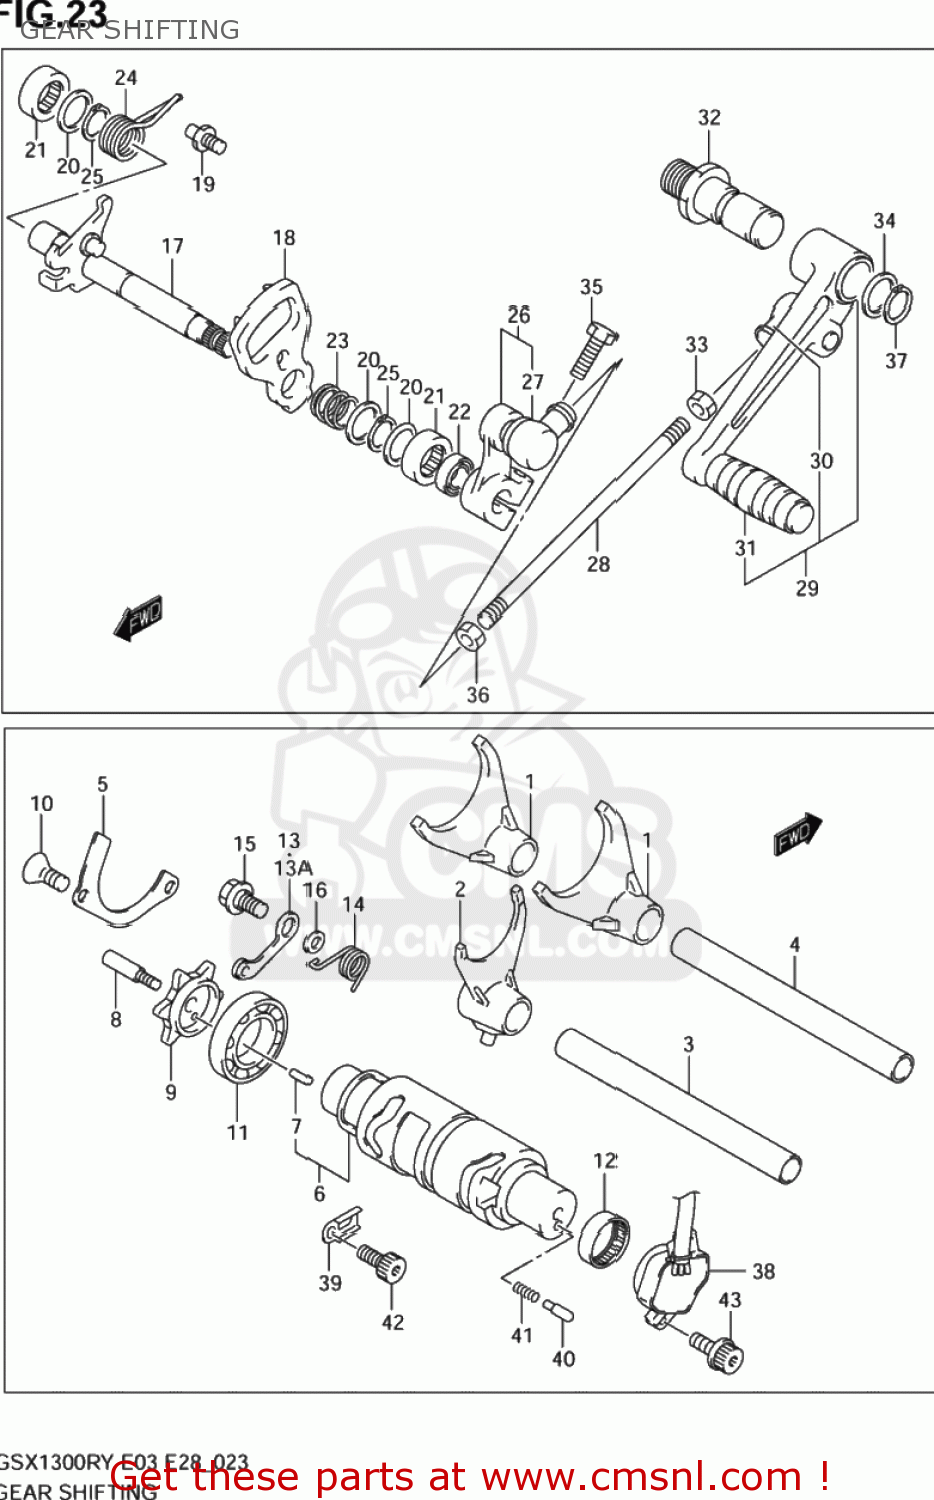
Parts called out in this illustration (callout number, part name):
1	FORK,GEAR SHIFT NO.1
2	FORK,GEAR SHIFT NO.3
3	SHAFT,SHIFT FORK NO.2(L:132)
4	SHAFT,GEAR SHIFT FORK(L:152)
5	RETAINER,SHIFT CAM BEARING
6	CAM,GEAR SHIFT
7	PIN
8	BOLT,GEAR SHIFT CAM PL
9	PLATE,GEAR SHIFT CAM
10	SCREW(6X12)
11	BEARING(25X47X8)
12	BEARING(25X32X12)
13	STOPPER,SHIFT CAM
13A	STOPPER,SHIFT CAM
14	SPRING,STOPPER ARM
15	BOLT(6X14.3)
16	WASHER
17	SHAFT,GEAR SHIFT
18	PLATE,GEAR SHIFT CAM DRIVE
19	STOPPER,GEAR SHIFT CAM
20	SHIM(14X22X1)
21	BEARING(14X20X12)
22	SEAL,OIL(14X22X6)
23	SPRING
24	SPRING
25	CIRCLIP
26	ARM,GEAR SHIFT LINK
27	COVER,DUST
28	ROD,GEAR SHIFT LINK
29	LEVER ASSY,GEAR SHIFT
30	COVER,DUST
31	RUBBER,GEAR SHIFT PEDAL
32	SHAFT,GEAR SHIFT LEVER
33	NUT
34	WASHER(12.5X20X1)
35	BOLT
36	NUT
37	CIRCLIP,12 MM
38	BASE ASSY,GEAR SHIFT TERMINAL
39	CLAMP,GENERATOR LEAD WIRE
40	PIN(5X15.5)
41	SPRING
42	BOLT
43	BOLT
